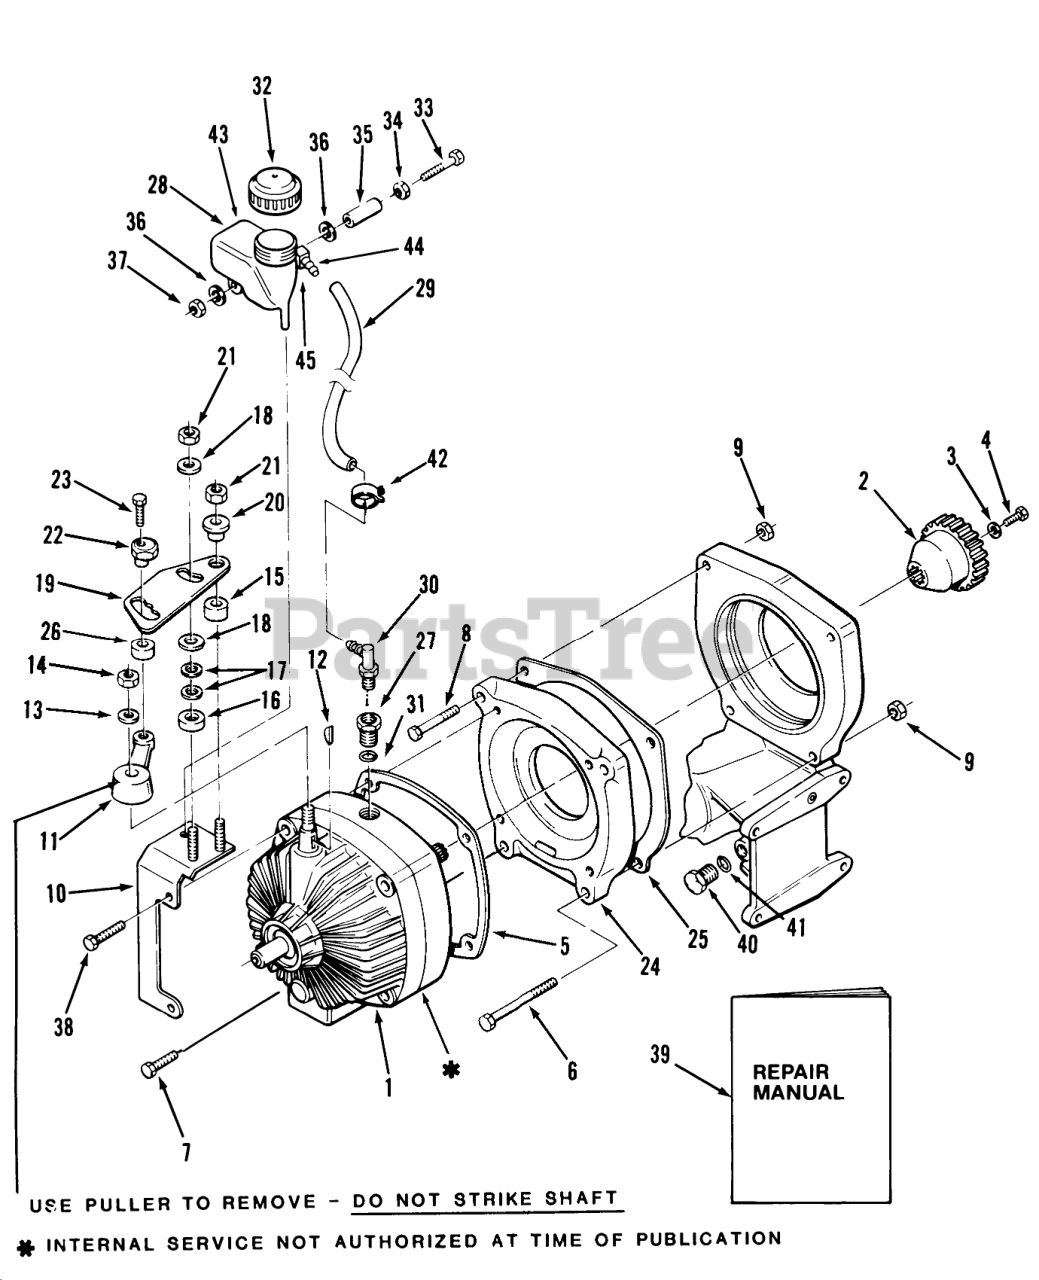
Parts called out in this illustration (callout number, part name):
1	TRANSMISSION HYDRO
2	GEAR 20TEETH DRIVE
3	WASHER
4	H H C S
5	GASKET HYDRO
6	H H C S
7	BLT SH 3/8-16X 1 1/4
8	BOLT SH 3/8-16X3 1/2
9	Nut
10	CONTROL SUPPORT ASSY R
11	ARM SPEED CONTROL
12	KEY WOODR 1/8X1/2 DI
13	Washer
14	NUT
15	SPACER-PIVOT
16	SPACER-FRICTION
17	WASHER-SPRING DISC
18	FRICTION WASHER
19	CAM-SPEED CONTROL (NS)
20	CAM-SPACER
23	Bolt
24	ADAPTER-HYDRO
25	GASKET
26	SPACER CAM
27	Plug Fitting w/O-ring
28	Tank Assembly(Includes elbow & rubber bushing)
29	Hose
30	FITTING-ELBOW
31	0-Ring
32	CAP VENTED B
33	BOLT 1/4-20 X 1 3/4
34	SPEED NUT
35	SPACER
37	Nut
38	Bolt
39	Repair Manual
40	PLUG-WITH O-RING
41	O-ring
42	Clamp
43	Reservoir Tank Only
44	FITTING
45	BUSHING
